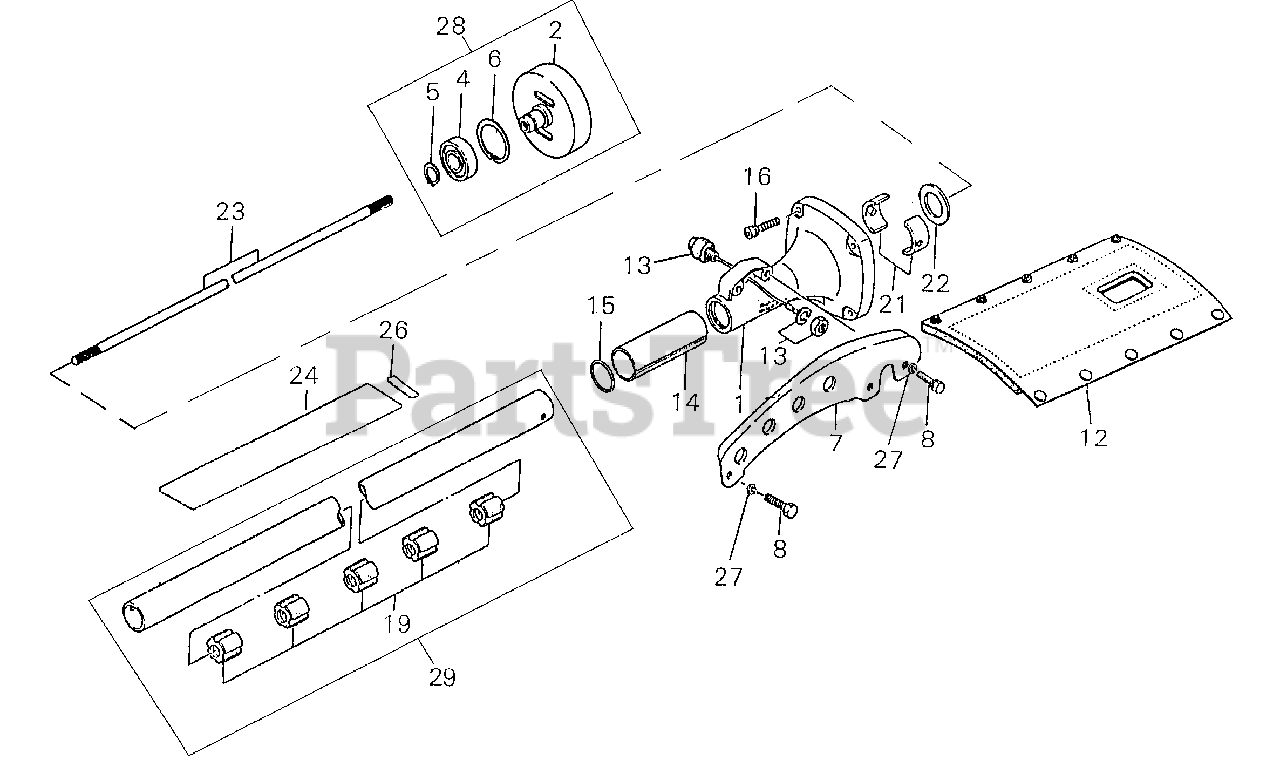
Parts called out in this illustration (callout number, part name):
1	HOUSING, CLUTCH
4	BEARING, BALL - 6202
5	RING, RETAINING - 15
6	RING, RETAINING - 35
7	HANGER
7	PROTECTOR
8	SCREW - 6X16
12	SWITCH, IGNITION
13	SWIVEL BUSHING
14	O-RING
15	SCREW - 6X28
16	MAIN PIPE ASSY
19	STOPPER
22	WASHER
23	DRIVESHAFT
24	LABEL - CAUTION
26	LABEL - ALIGNMENT
27	LOCKWASHER - 6
28	CLUTCH DRUM ASSY
28	DRUM, CLUTCH
29	STOPPER
31	LABEL - CAUTION
